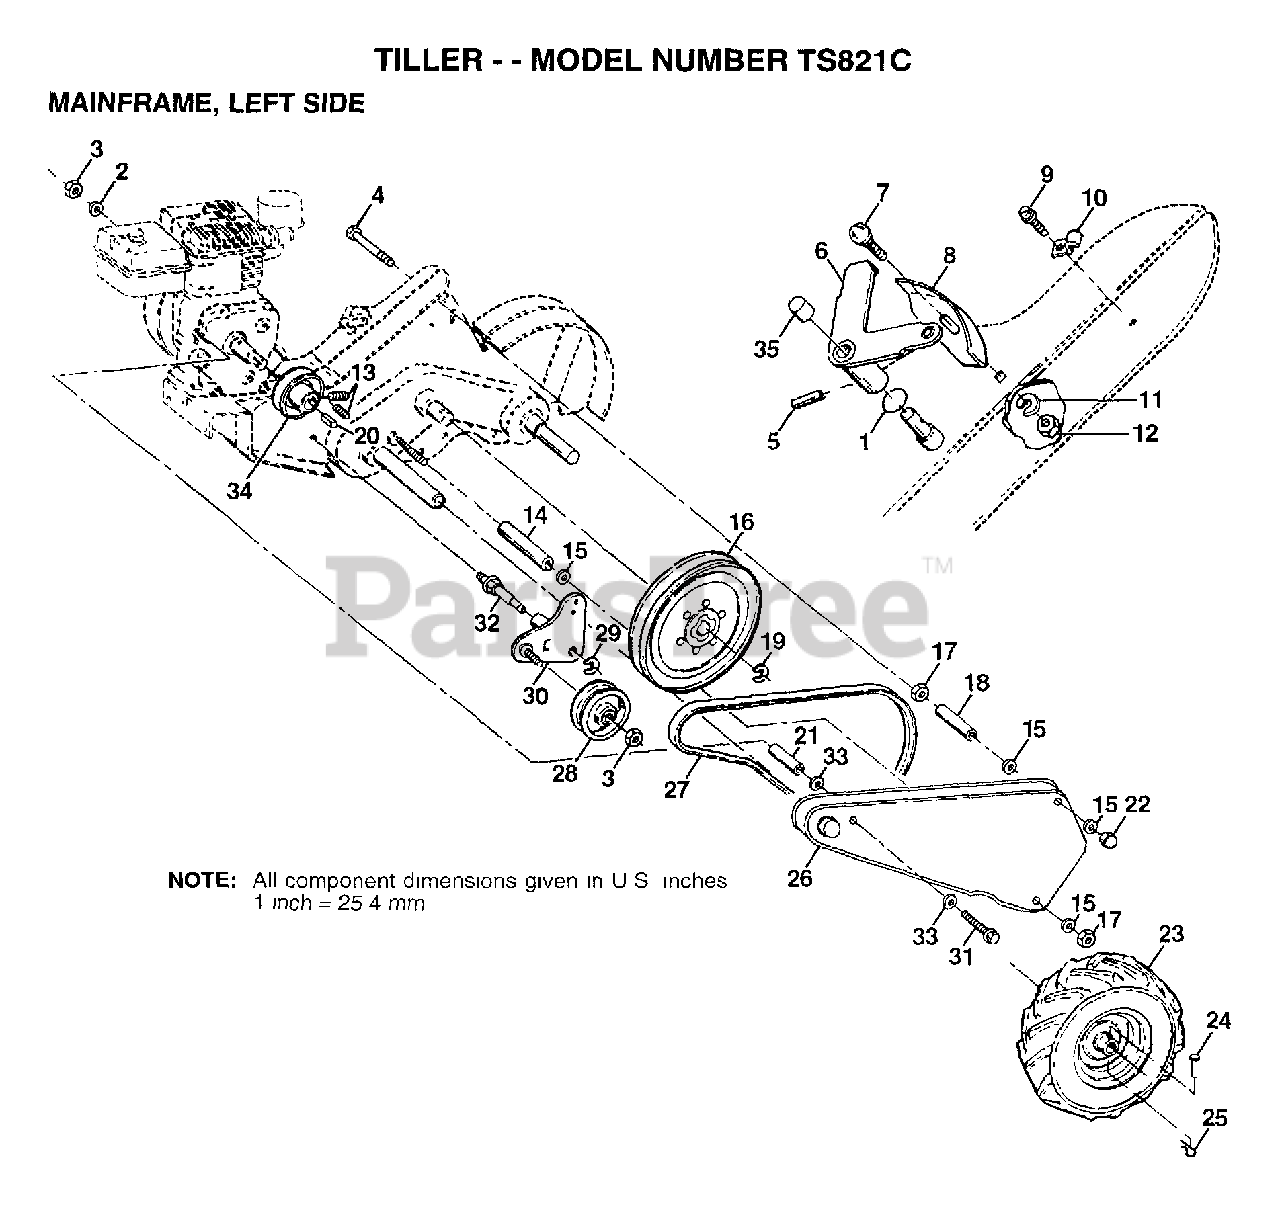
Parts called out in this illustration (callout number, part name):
1	O-RING TI
2	LOCKWASHER
3	NUT.HEX.3/8-16UNC
4	BOLT TI
6	LEVER ASM CRT
7	BOLT
8	PANEL TI
10	CONDIUT CLIP T
11	LOCKWASHER
13	SET SCREW
14	SPACER TI
15	WASHER
16	SHEAVE.TRANS.
17	NUT.HEX.5/16-18
18	SPACER TI
20	KEY TI
21	SPACER.SPLIT
22	NUT TI
23	TIRE TI
24	RIVET.PAN HD.1.75
25	SPRING.RETAINER
26	GUARD BELT RED
27	BELT.DRIVE
29	KLIP RING
31	BOLT1/2-20UNF2.75
32	SHAFT.IDLER
34	SHEAVE CRT
35	CAP PLUNGER BLACK
